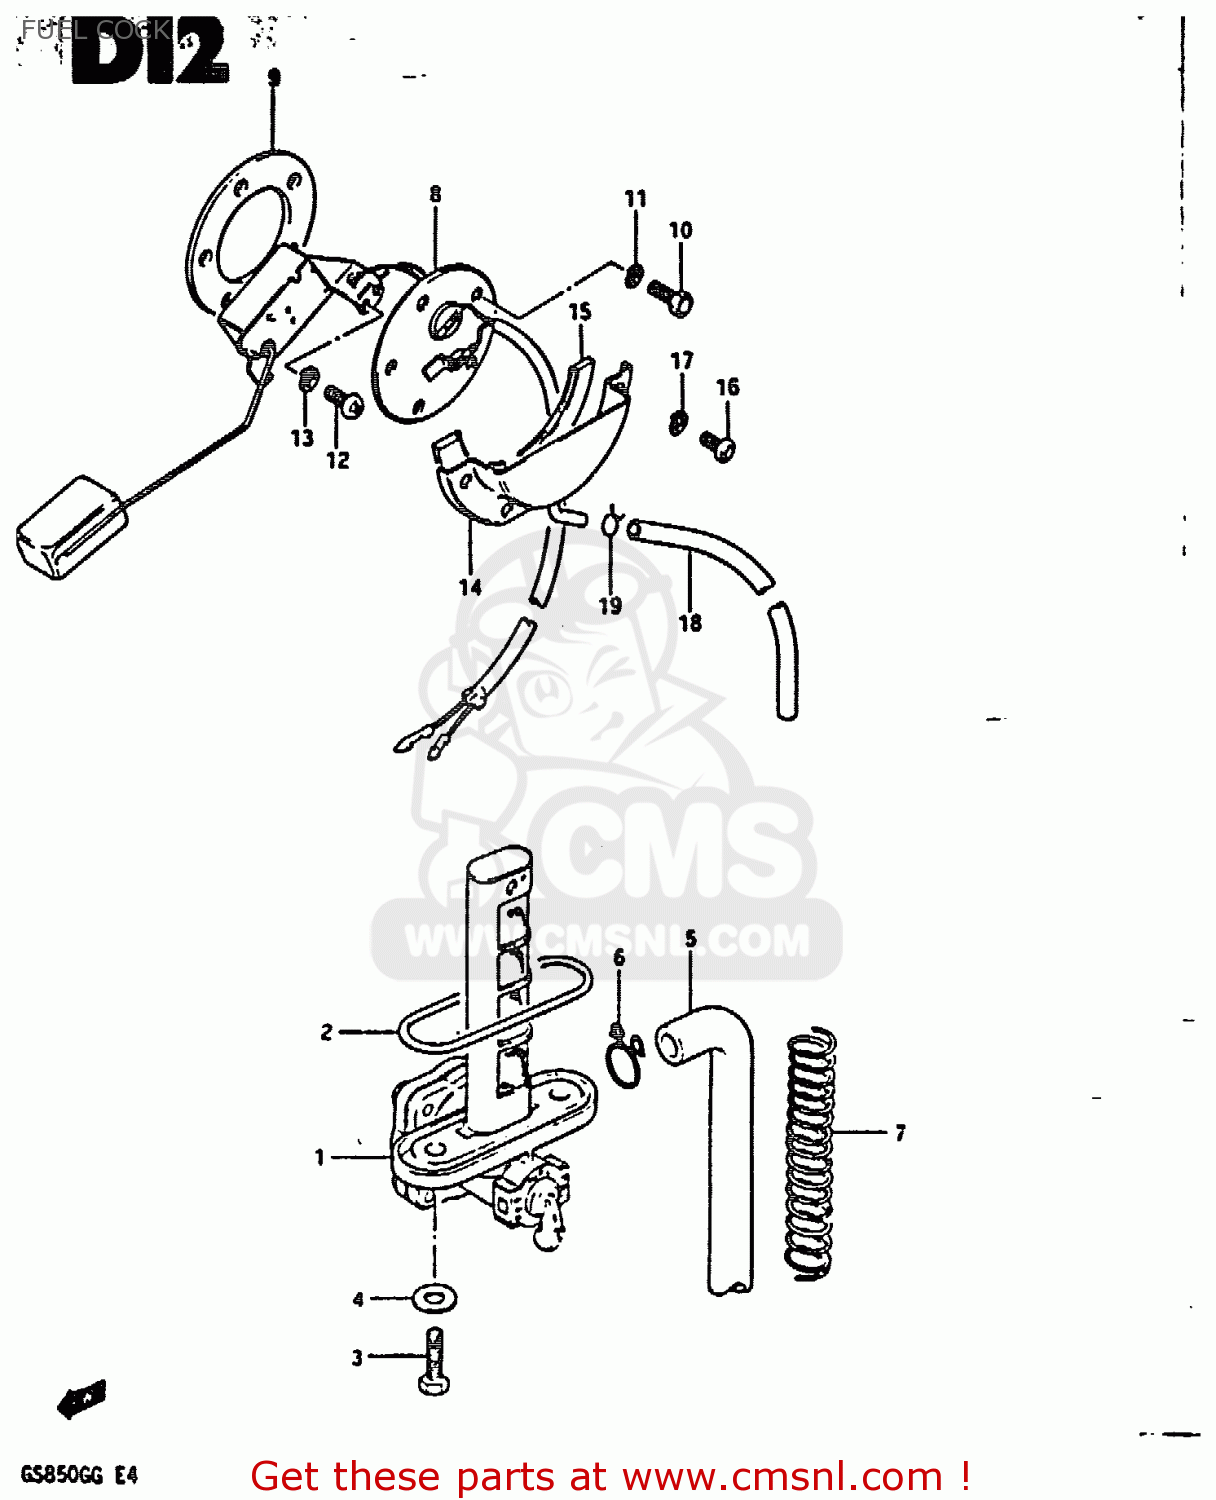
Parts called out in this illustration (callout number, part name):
1	COCK ASSY,FUEL
2	O RING
3	BOLT(6X20)
4	GASKET
5	HOSE
6	CLIP
7	SPRING
8	GAUGE ASSEMBLY,FUEL LEVEL
9	GASKET,FUEL LEVEL GAUGE (NAS)
10	BOLT
11	LOCK WASHER
12	SCREW 5X10
13	LOCK WASHER
14	PLATE,FUEL DRAIN
15	GASKET (NAS)
16	SCREW
17	LOCK WASHER
18	HOSE,FUEL
19	CLIP
